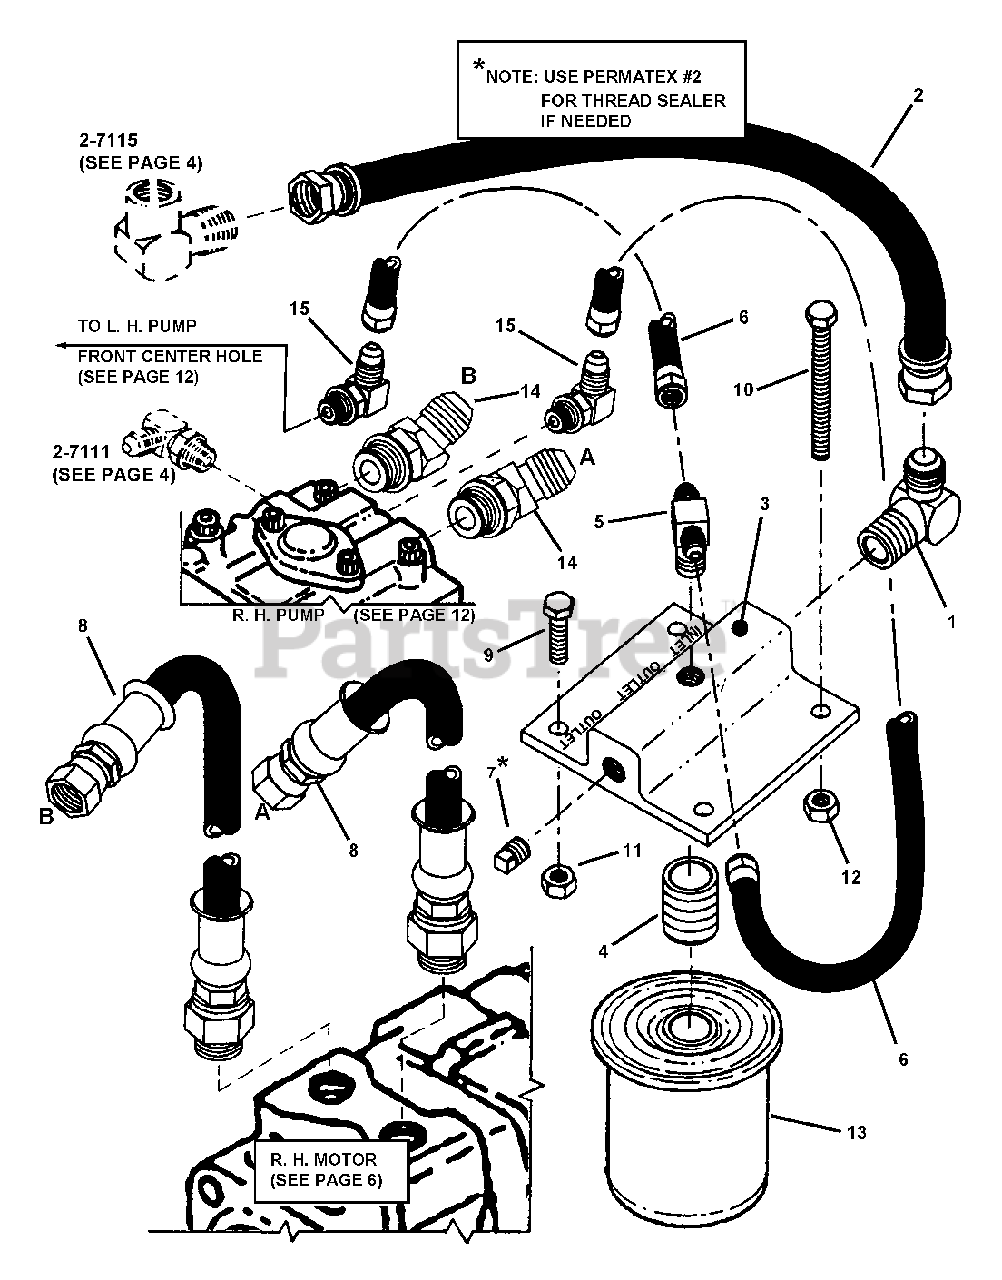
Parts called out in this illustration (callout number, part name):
1	FITTING, External 90 degree w/37 degree Flare
2	HOSE, 1/2 x 16-1/2" Long
3	MOUNT, Oil Filter
4	FITTING, Straight 1-12 UNF Thread
5	TEE
6	HOSE, 10-1/2"
7	PLUG, 1/4 NPTM Pipe
8	HOSE, Pump/Motor, High Pressure 21-1/2"
9	BOLT, 5/16-18 X 1 GD5 YZ
10	SCREW, 3/8-16 x 3-1/2" Hex Head Cap, Grade 5
11	NUT, 5/16-18 HEX NYLON LOCK
12	NUT, 3/8-16 HEX NYLON LOCK
13	FILTER, Oil
14	FITTING, 45 degree w/"O"-Ring Boss
15	FITTING, 90 degree - "O"-Ring Boss
